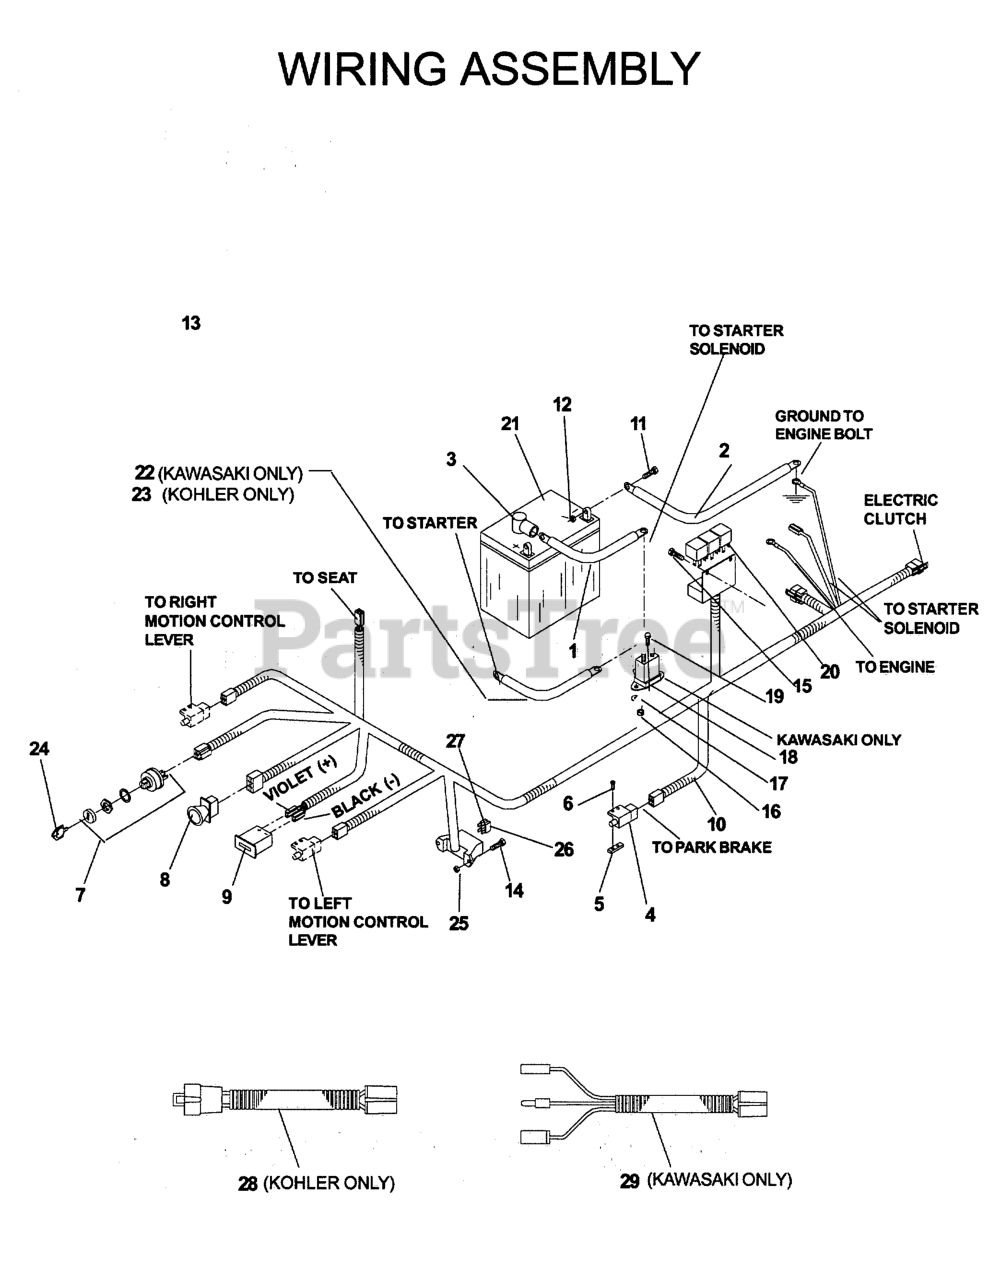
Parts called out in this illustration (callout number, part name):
1	CARBURETOR
3	NOZZLE ASSY
5	INLET NEEDLE
6	SPRING
8	PIN RETAINING SCREW
10	CAP ZAMA 0051034
11	SHAFT ASSY
12	COLLAR ZAMA 005020
17	CHOKE SHAFT ASSY
24	THROTTLE SHAFT ASSY
42	GASKET KIT
